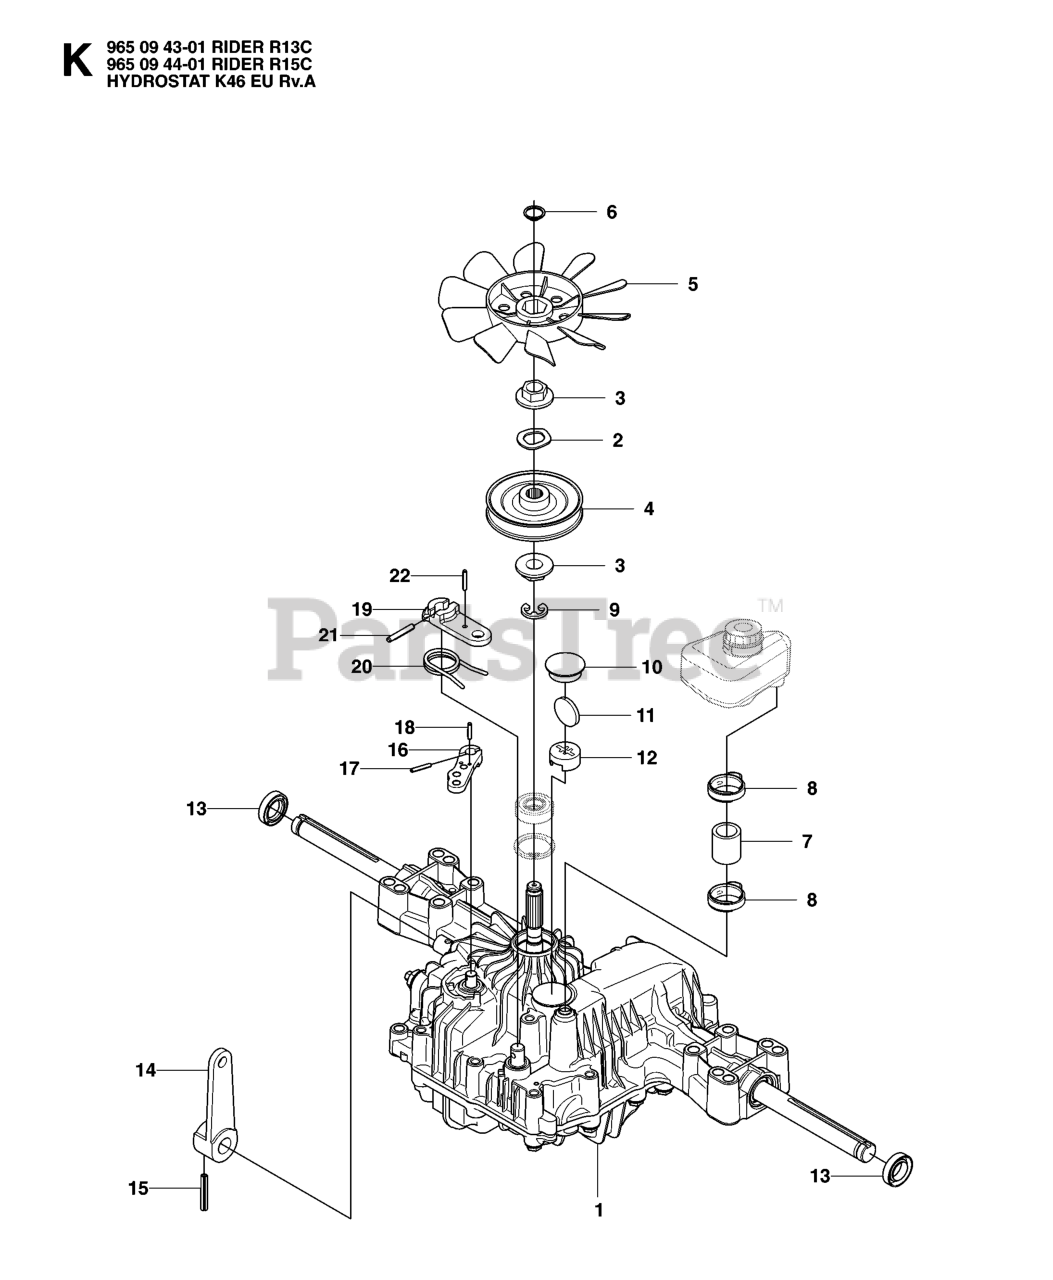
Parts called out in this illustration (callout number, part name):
1	REPL BY 506 98 63 01
4	PULLEY - 3 1/2"
5	FAN.BLACK.1A646083070
6	RETAINING RING **
7	PIPE
8	CLAMP
9	Retaining Ring
13	RP SEAL.19, 19216334280
20	RETURN SPRING
